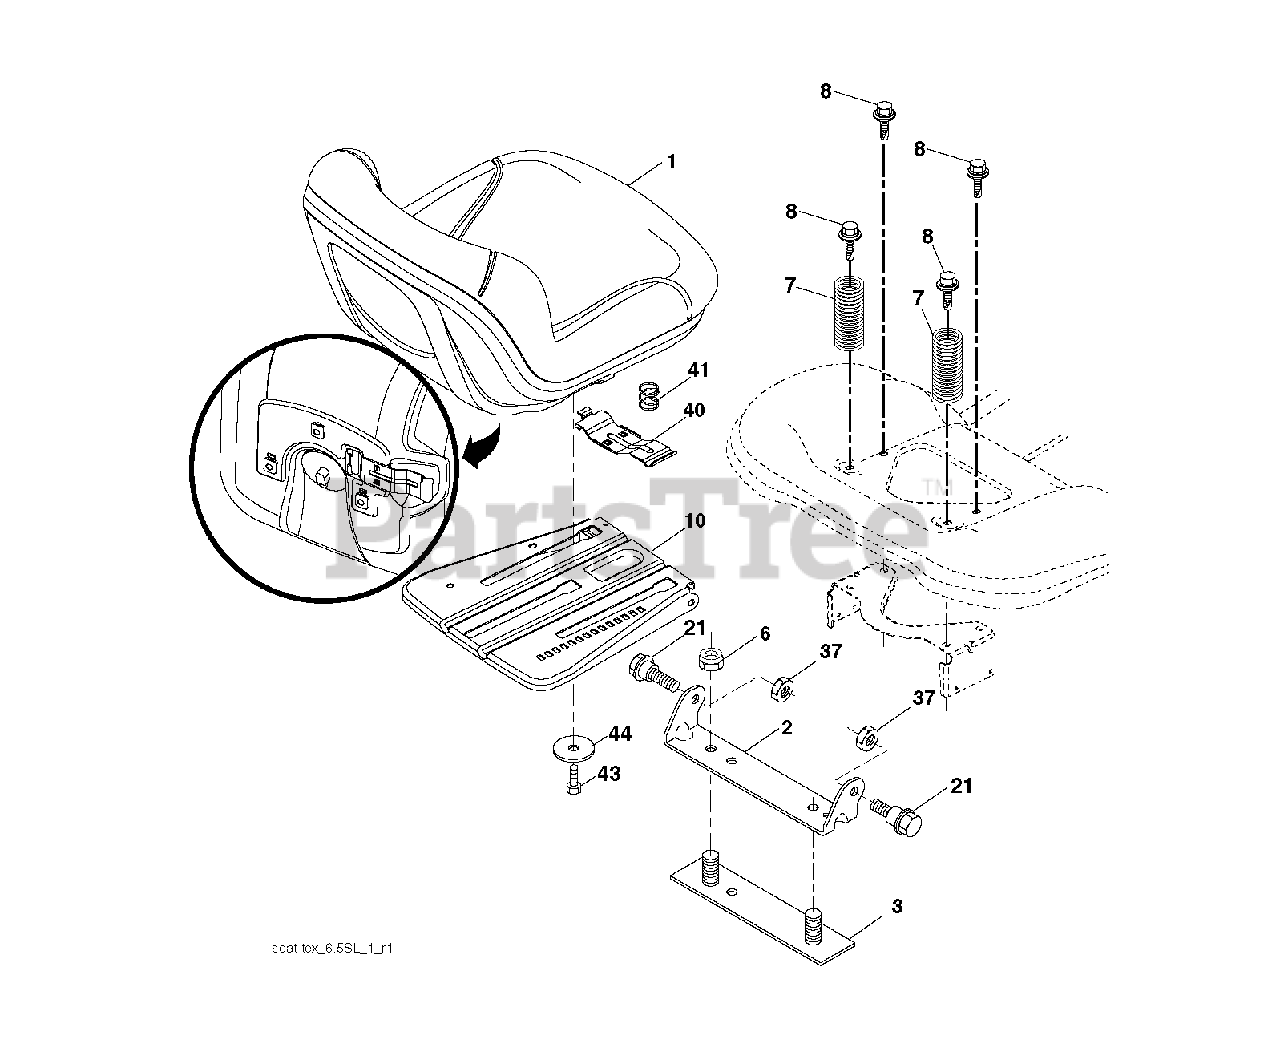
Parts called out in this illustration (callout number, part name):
1	SEAT.TG130.BLACK.NO/LOGO.
2	BRKT.PIVOT.FENDER
6	NUT
7	SPRING COMPRESSION
8	BOLT, 5/16-18 X 1 3/4
10	PAN.ASM.SEAT.3PT
21	BOLT.SHOULDER.5/16-18
37	NUT.71038.31-18.HEX.NYLOCK
40	HANDLE.SLIDE.SEAT.TEX.BLACK
41	SPRING.LATCH.SEAT.TEX
44	WASHER 13/32 X 2-3/8 X 12GA
